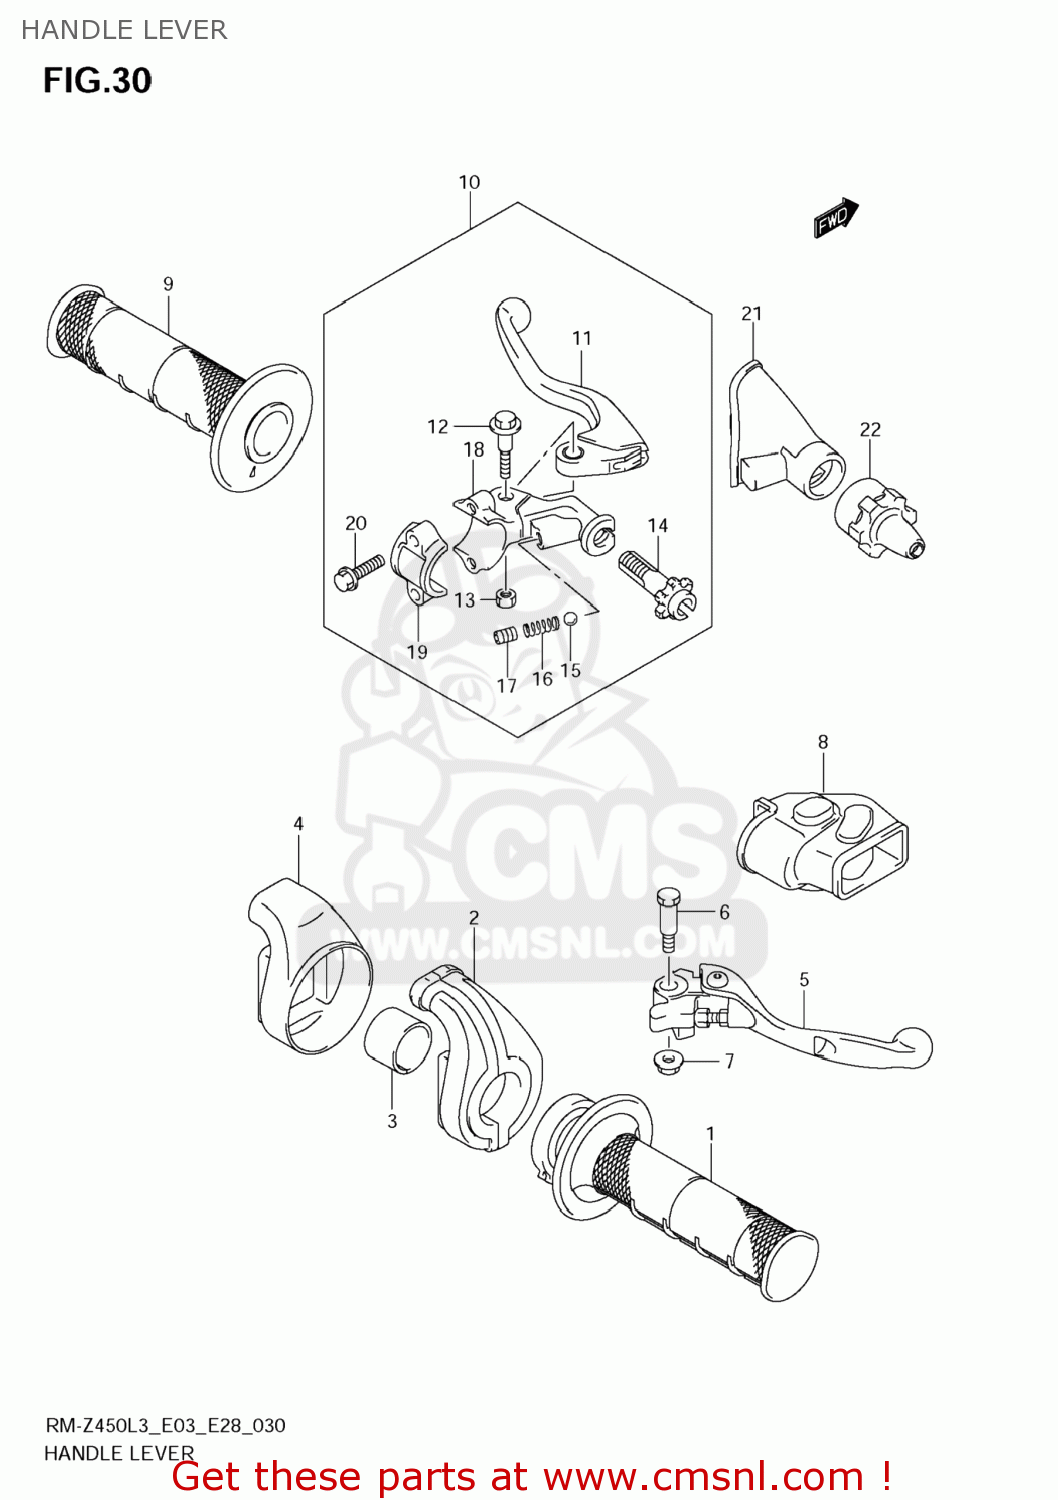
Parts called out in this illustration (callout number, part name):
1	GRIP,THROTTLE
2	CASE ASSY,THROTTLE
3	COLLAR,THROTTLE CASE
4	COVER,THROTTLE CASE
5	LEVER ASSY,BRAKE
6	BOLT,BRAKE LEVER
7	NUT
8	COVER,BRAKE LEVER
9	GRIP,L
10	LEVER ASSY,CLUTCH
11	LEVER,CLUTCH
12	BOLT
13	NUT
14	ADJUSTER,CLUTCH CABLE
15	BALL
16	SPRING
17	SCREW(6X8)
18	HOLDER,CLUTCH LEVER
19	BRACKET,CLUTCH LEVER HOLDER
20	BOLT,BRACKET
21	COVER,CLUTCH LEVER
22	COVER,CLUTCH ADJUSTER
